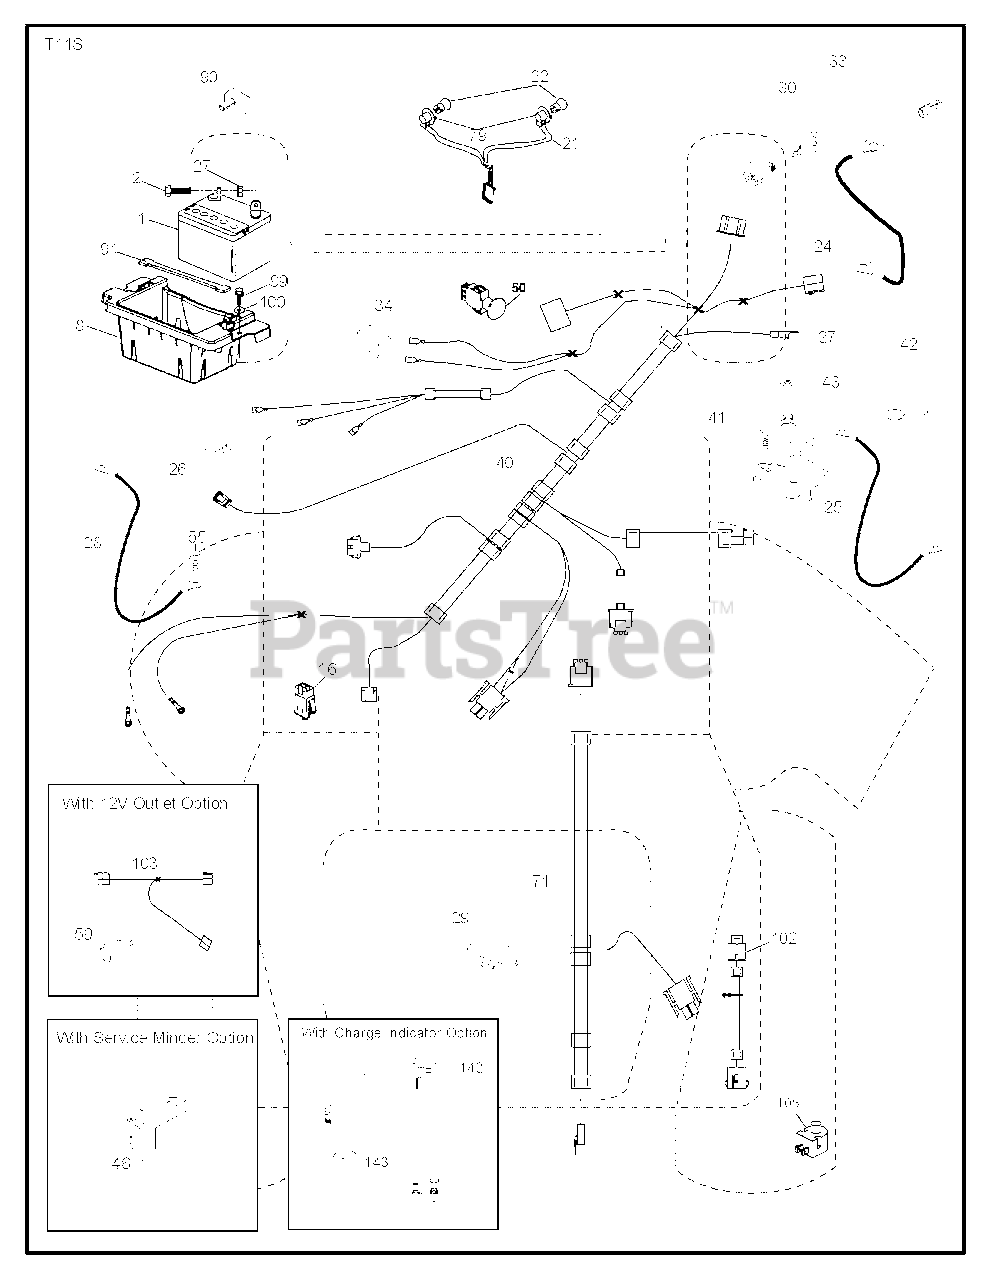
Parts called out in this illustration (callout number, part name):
1	Battery, Dry 30 Amp
2	BOLT.HEX.1/4.X.3/4.DICHROMATE
8	BOX.BATTERY.MOUNT.FRONT.LT
16	SWITCH INTERLOOK PUSH-IN
21	HARNESS.LIGHT W/4152J BULBS
24	CABLE.BATT.POS.WIRE.TG.DA SOL
25	CABLE.STARTER.6G.BL/RED.17.5
26	FUSE 20AMP
27	NUT
28	CABLE GROUND 6 GA 21" 90T BLK
29	SWITCH.SEAT.DELTA.OPC.
30	SWITCH.IGN.DELTA.W.LGH.ROS
33	KEY.CHAIN.BLISTER.PACK.GEN.INT
40	HARNESS-CHASSIS SUB
41	SCREW
42	TERMINAL COVER
43	SOLENOID.W/BRASS.PLUNGER
46	RP GUAGE.SRVCMNDR.HRMTR.
50	RB PTO.SWITCH.8 TERMINAL.BLACK
55	SCREW 5/16"
71	HARNESS.IGN.DASH.HUSQ/PRED
79	BULB HOLDER ASM.
90	COVER.TERMINAL.BATTERY
91	STRAP.BATTERY.MOUNT.FRONT(2 2)
99	SCREW HEXWSHR 1/4-20X3/4
102	REVERSE SWITCH
105	HARNESS PIGTAIL PCH TEX ROS
